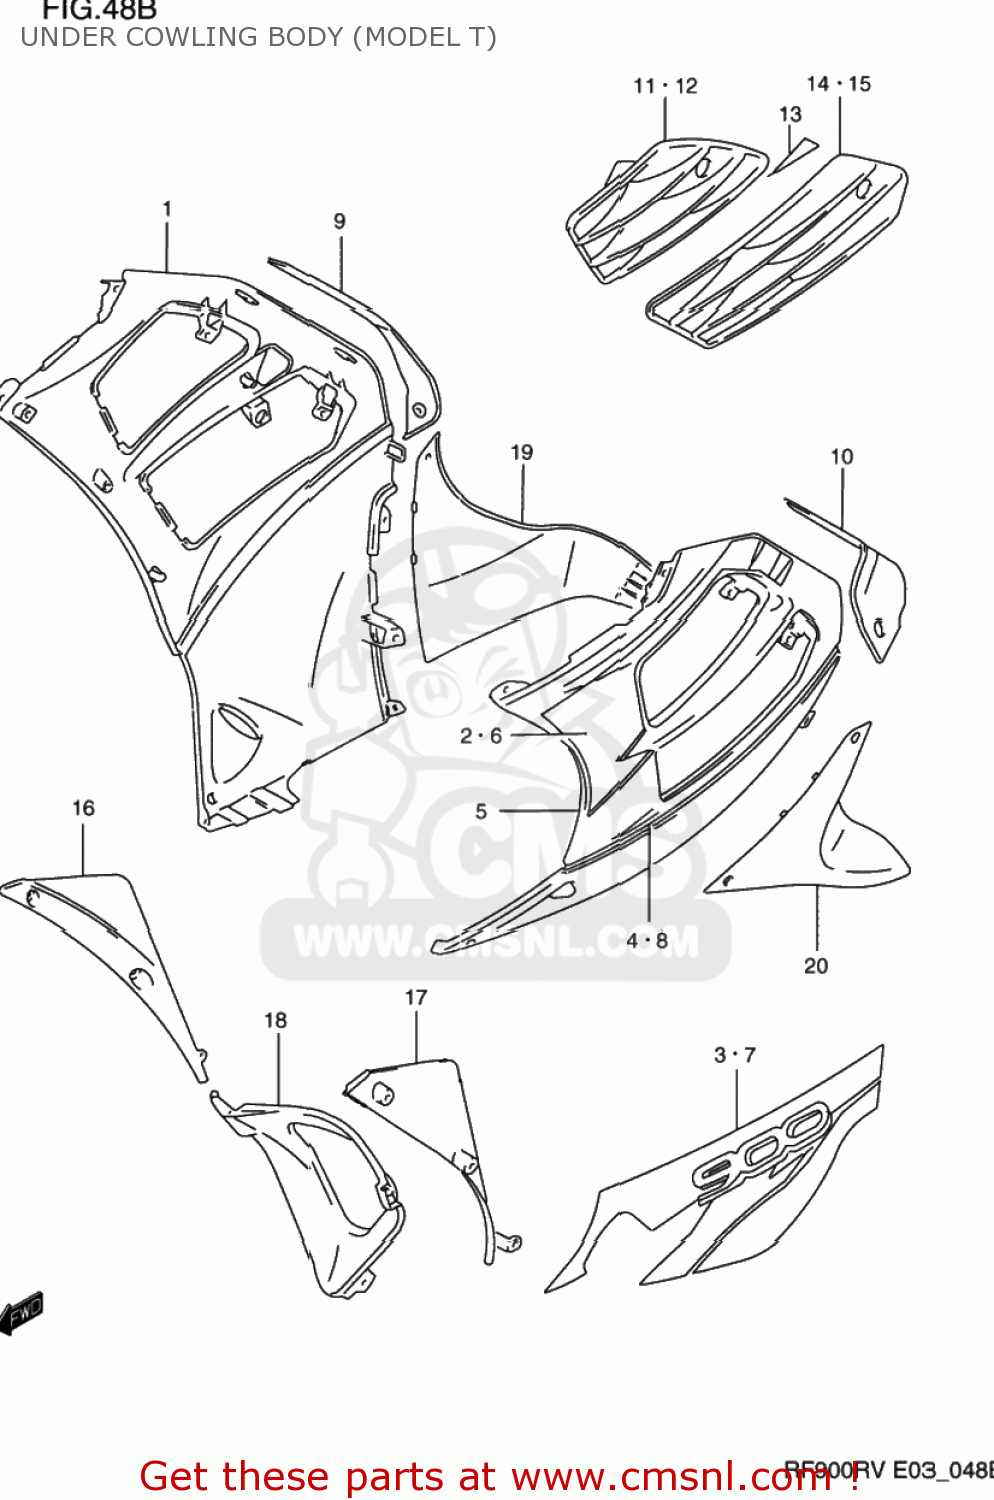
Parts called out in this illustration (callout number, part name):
1	COWLING ASSY,UNDER,R(PURPLE)
2	TAPE SET,UNDER UPR,R
3	TAPE,UNDER,LOWER,RIGHT
4	TAPE,UNDER COWL,R
5	COWLING ASSY,UNDER,L(PURPLE)
6	TAPE SET,UNDER UPR,L
7	TAPE,UNDER LWR,L
8	TAPE,UNDER COWL,L
9	PANEL,UNDER,R
10	PANEL,UNDER,L
11	COVER,UNDER UPR,R
12	COVER,UNDER UPR,L
13	TAPE,UNDER COVER,L
14	COVER,UNDER COWL LWR,R
15	COVER,UNDER COWL LWR,L
16	COWLING,UNDER INNER,R
17	COWLING,UNDER INNER,L
18	COWLING,UNDER CTR
19	COWLING,UNDER RR,R
20	COWLING,UNDER RR,L
